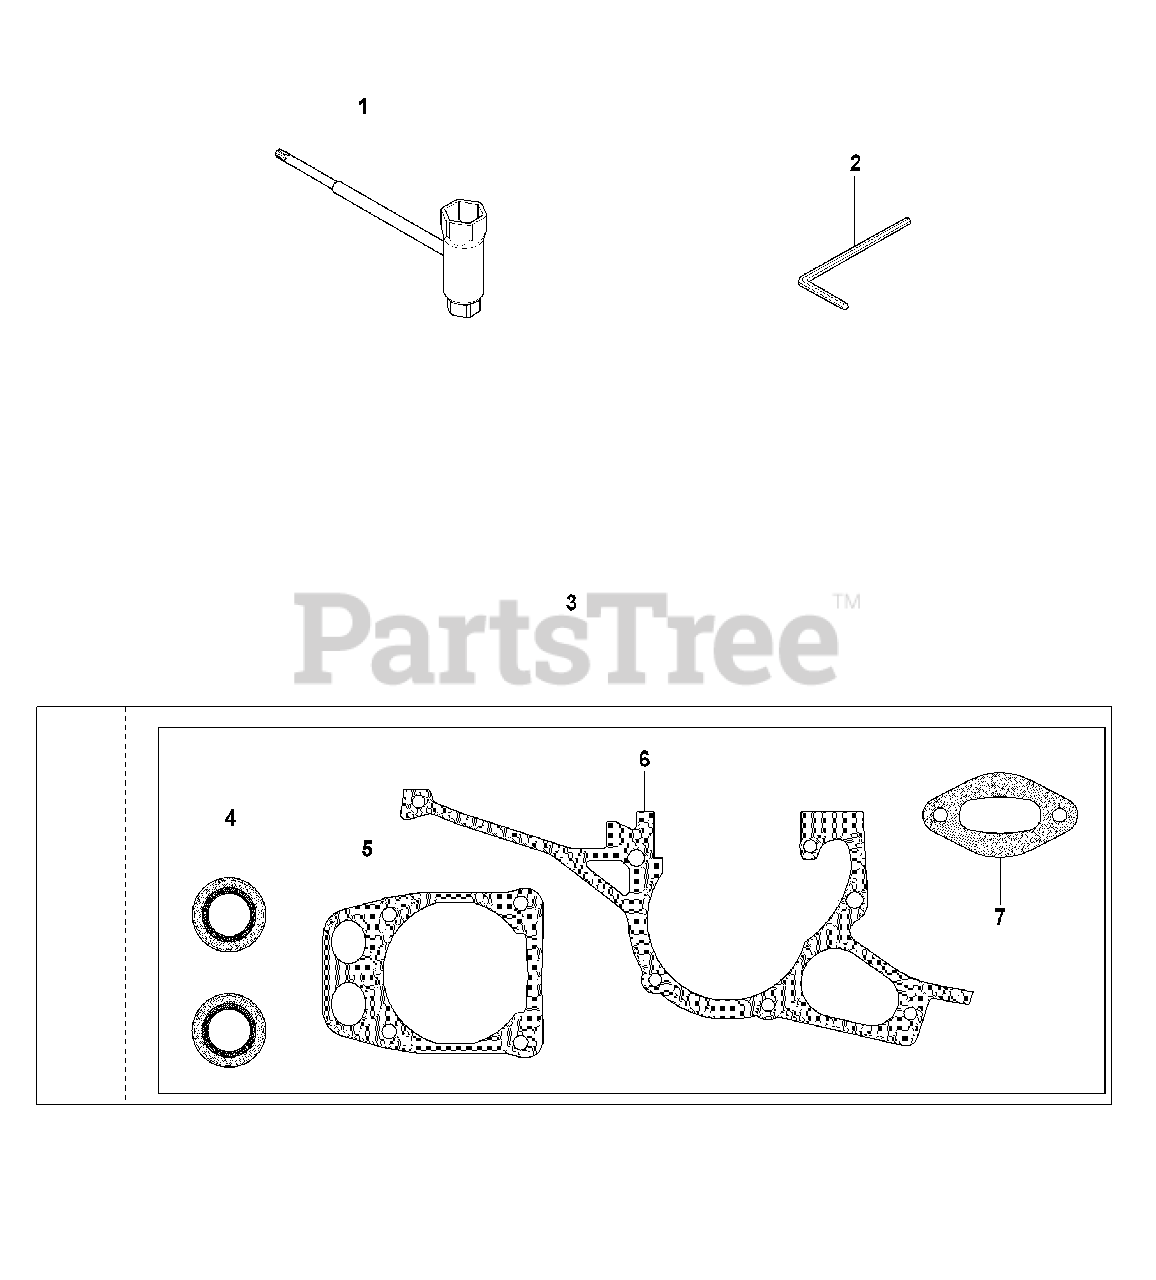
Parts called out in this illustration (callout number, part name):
1	COMBINATION TOOLTorx 27
2	L-SPANNER4 mm
3	GASKET KITIncl. 4, 5, 6, 7
4	SEALING RING
5	GASKET
7	GASKET MUFFLER
